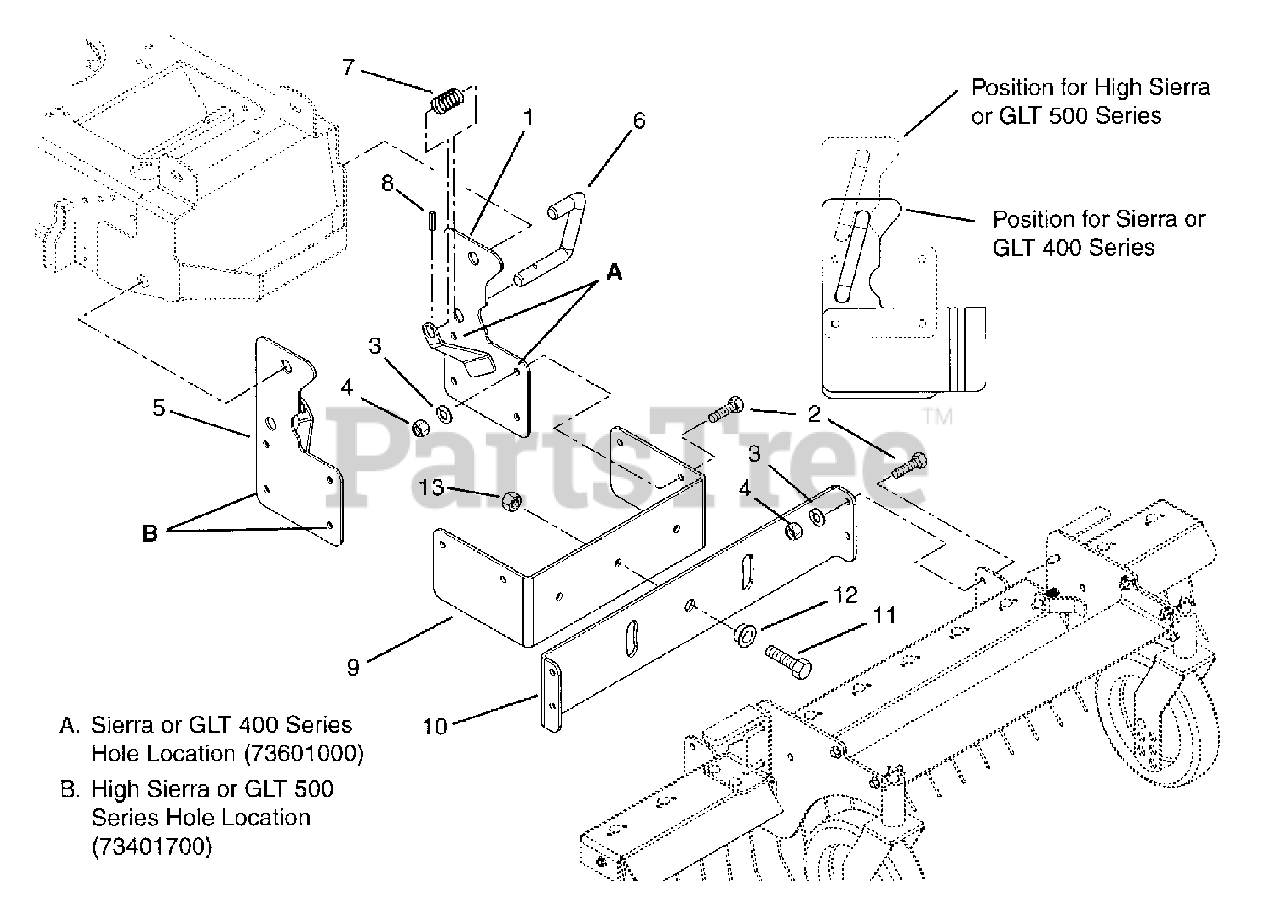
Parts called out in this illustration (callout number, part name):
1	Pivot-Frame Left Hand
2	Bolt-Hex .31-18 x .75 Grade 5
3	Washer-Lock .312 x .097
4	Nut-Hex .31-18
5	Pivot-Frame Right Hand
6	Pin-Latch
7	Spring-Compression .072 x .77 x 1.75
8	Pin-Roll .188 x 1.00
9	Stabilizer-Pivot Frame
10	Stabilizer-Channel Support
11	Bolt-Hex .38-16 x 1.00 Grade 5
12	Bushing-Flange .390 x .625 x .328 x .875
13	Nut-Hex .38-16
